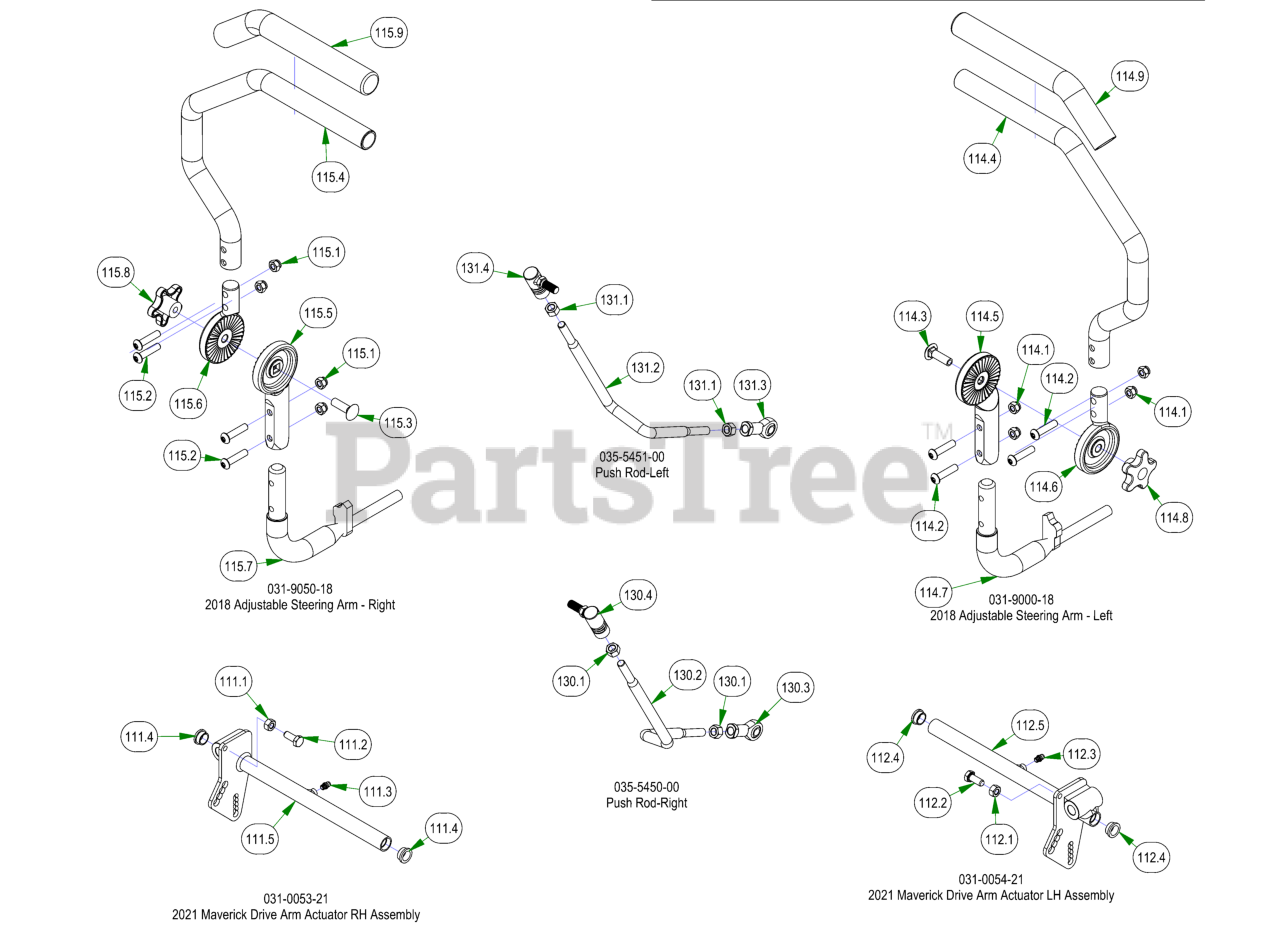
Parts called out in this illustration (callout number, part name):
111	2021 Maverick Drive Arm Actuator RH Assembly
111.1	5/16-18 HEX NUT ZINC
111.2	5/16-18 X 3/4 HEX CAP SCREW (GR.5) ZINC
111.3	1/4" Press in Grease Fitting
111.4	2019 Drive Arm Bushing
111.5	2021 Drive Actuator RH Weldment
112	2021 Maverick Drive Arm Actuator LH Assembly
112.1	5/16-18 HEX NUT ZINC
112.2	5/16-18 X 3/4 HEX CAP SCREW (GR.5) ZINC
112.3	1/4" Press in Grease Fitting
112.4	2019 Drive Arm Bushing
112.5	2021 Drive Actuator LH Weldment
114	2018 Adjustable Steering Arm - Left
114.1	5/16-18 NYL INS L/N ZC
114.2	5/16-18 UNC X 1-3/8" BHCS, TORX DRIVE, GR 5
114.3	3/8-16 X 1-1/4 CARRIAGE BOLT ZINC
114.4	Upper Tube-Adjustable Steering
114.5	2018 Lower Adjuster - Steering Arm- Left
114.6	2018 Upper Adjuster - Steering Arm- Left
114.7	Steering Arm Elbow (Left)
114.8	Black Knob for Adjustable Steering Arm
114.9	Rubber Grip
115	2018 Adjustable Steering Arm - Right
115.1	5/16-18 NYL INS L/N ZC
115.2	5/16-18 UNC X 1-3/8" BHCS, TORX DRIVE, GR 5
115.3	3/8-16 X 1-1/4 CARRIAGE BOLT ZINC
115.4	Upper Tube-Adjustable Steering
115.5	2018 Lower Adjuster - Steering Arm- Right
115.6	2018 Upper Adjuster - Steering Arm- Right
115.7	Steering Arm Elbow (Right)
115.8	Black Knob for Adjustable Steering Arm
115.9	Rubber Grip
130	Push Rod-Right
130.1	3/8" Fine Threaded Jam Nut
130.2	Push Rod - Right (Rod Only)
130.3	Spherical Rod End - Outlaw
130.4	Quick Release Ball Joint
131	Push Rod-Left
131.1	3/8" Fine Threaded Jam Nut
131.2	Push Rod LH (Rod Only)
131.3	Spherical Rod End - Outlaw
131.4	Quick Release Ball Joint
